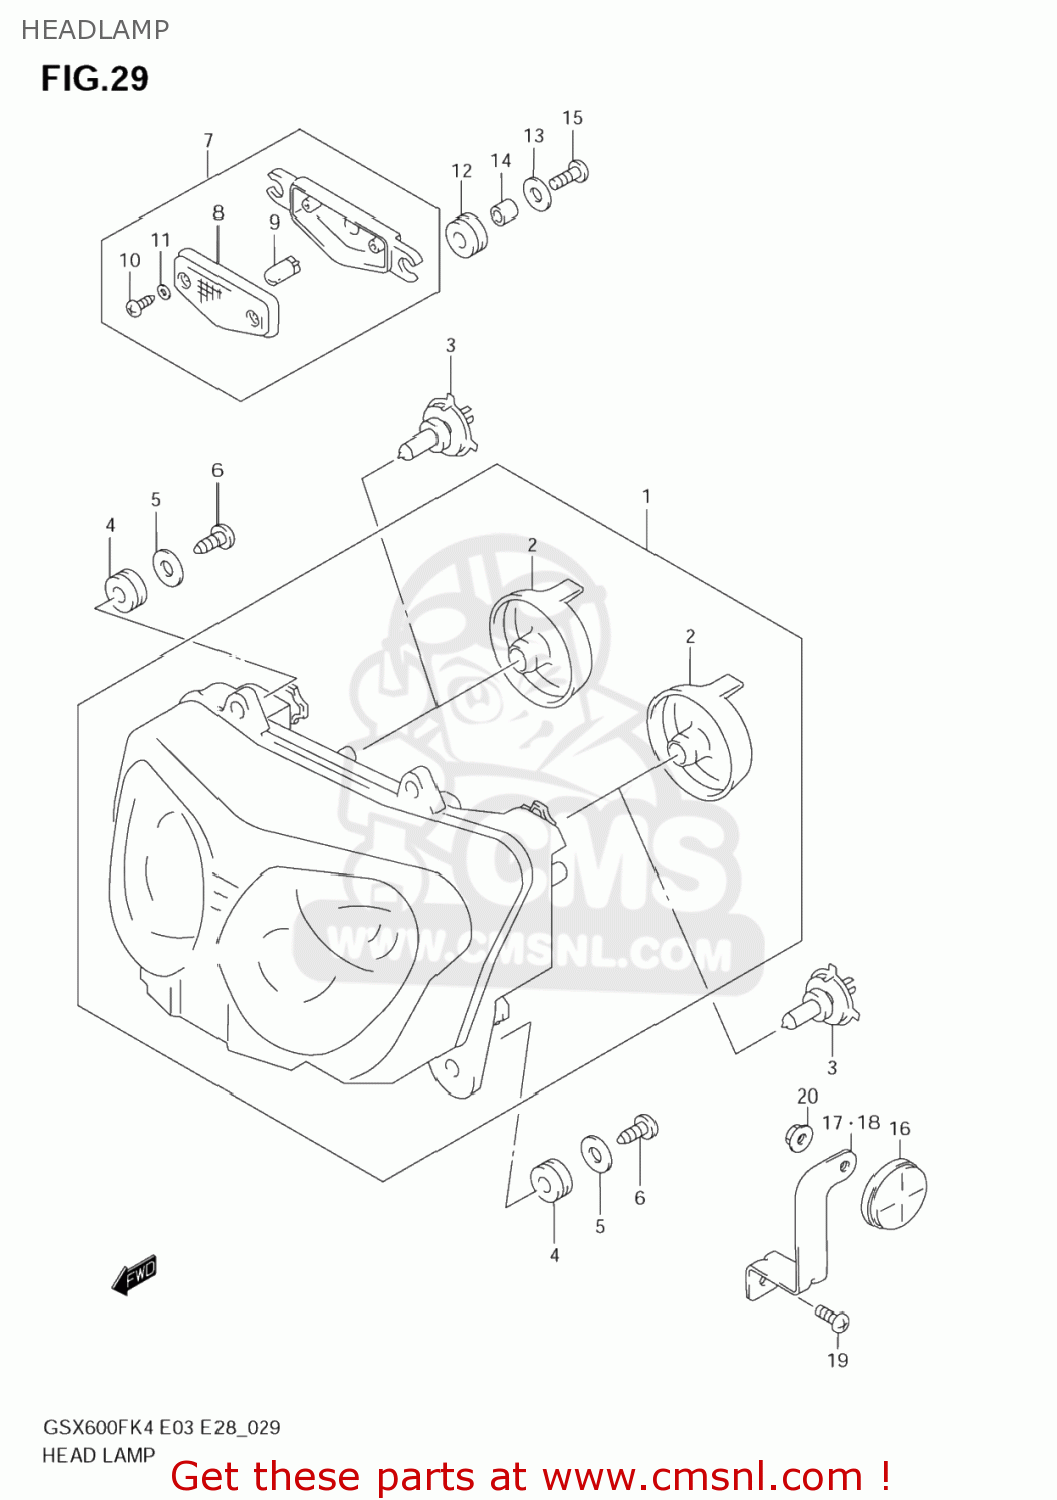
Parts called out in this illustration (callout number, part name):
1	HEADLAMP ASSY
2	COVER,SOCKET
3	BULB(12V60/55W,H4)
4	CUSHION,HEADLAMP
5	WASHER(5.5X18X1)
6	SCREW
7	LAMP ASSY,FR POSITION
8	LENS
9	BULB(12V5W)
10	SCREW
11	WASHER
12	CUSHION
13	WASHER(5.5X18X1)
14	SPACER(5.5X8X10.5)
15	SCREW 5X20
16	REFLECTOR,REFLEX FR
17	BRACKET,FR SIDE
18	BRACKET,FR SIDE RR,L
19	SCREW
20	NUT
